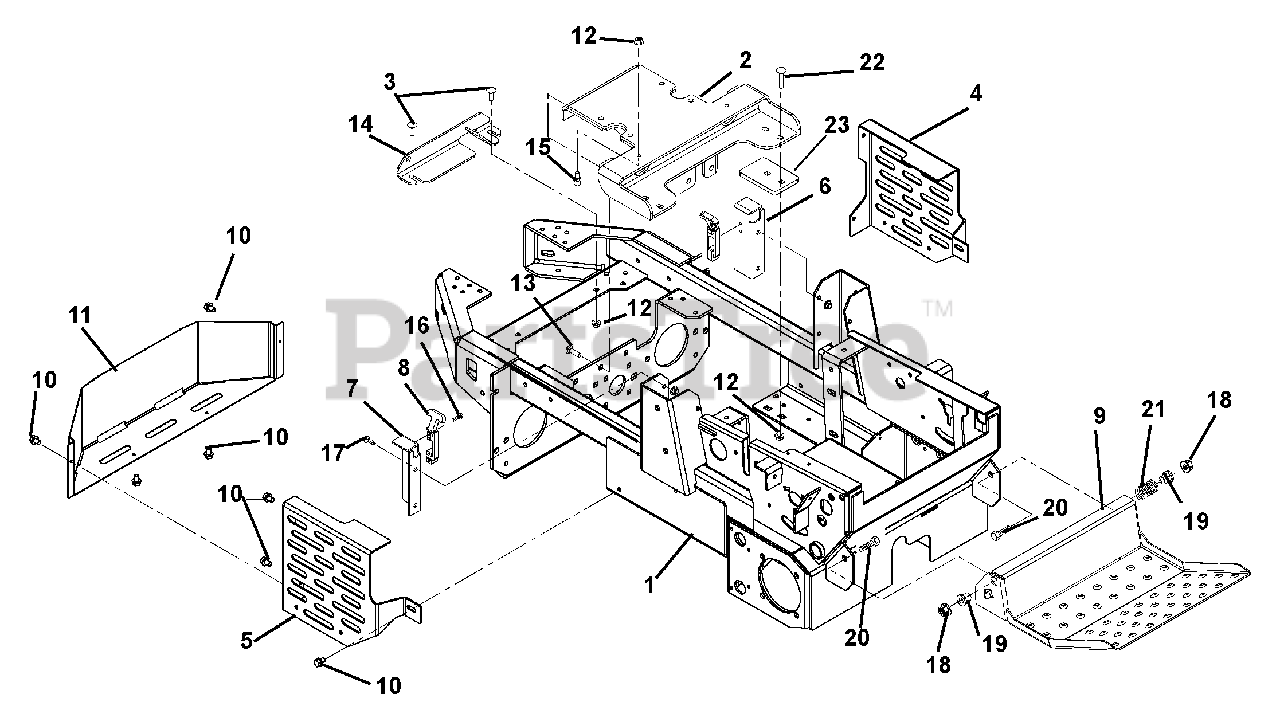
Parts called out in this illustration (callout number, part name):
1	Weldment, Frame
2	Plate, Kohler Engine Mounting
3	Bolt, Round Head Square Neck .38-16 x 1.00 Grade 5
4	Guard, Hose Fitting-LH Hand
5	Guard, Hose Fitting-RH Hand
6	Bracket, Left Hand Hood Mounting
7	Bracket, Right Hand Hood Mounting
8	Latch, Rubber
9	Weldment, Foot Plate
10	Screw, Tapping .38-16 x .75 Hex Washer Head
11	Guard, Pump Belt
12	Nut, .38-16 Nyloc Flange
13	Bolt, Round Head Square Neck .38-16 x 1.25 Grade 5
14	Weldment, Clutch Stop
15	Stud, Ball
16	Screw, Machine 10-24 x .50 Hex Washer Head
17	Screw, Tapping .38-16 x .50 Hex Washer Head Thread Rolling
18	Nut, Locking-Top-Flange .50-13
19	Bushing, Flange .515 x .746 x 1.290 x 1.000
20	Bolt, Hex .50-13 x 2.25 Grade 5
21	Spring, Compression .085 x .80 x 1.00 WLD36
22	Bolt, Round Head Square Neck .38-16 x 1.75 Grade 5
23	Strap, Engine Mounting Support
